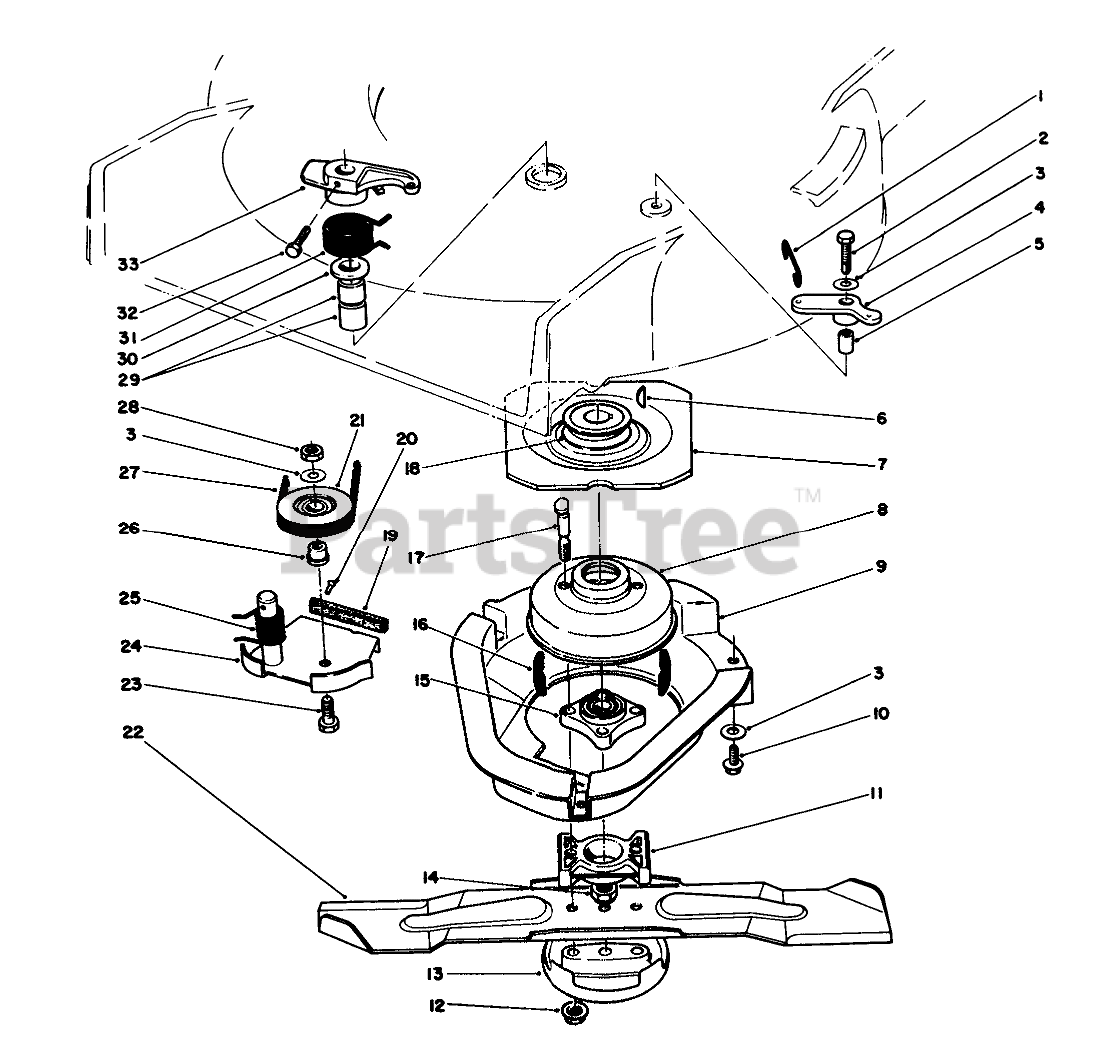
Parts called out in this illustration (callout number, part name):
1	LINK-CONTROL
2	Screw-Self Tap Hex Hd.
3	WASHER-PLAIN
4	BELLCRANK
5	SLEEVE-BELLCRANK
6	KEY-WOODRUFF
7	Flywheel
8	Drum-Brake
9	SHIELD BBC
10	SCREW-HWHTF
11	SPACER-BLADE
12	NUT-LOCK
13	Anti Scalp Cup
14	NUT-LOCK, NI
15	HUB ASM
16	DAMPENER-VIBRATION
17	BOLT-BLADE
18	PULLEY
19	Pad-Brake
20	.185 DIA X .375 RT +
21	PULLEY-IDLER
22	BLADE-21in
23	SCREW-HH
24	Brake Plate (Incl. Ref. #19 & 20)
25	SPRING-TORSION
26	HUB-PULLEY, IDLER
27	V-BELT
28	NUT-LOCK, NI
29	BEARING
30	WASHER
31	SPRING-TORSION
32	SCREW-HH
33	LEVER
